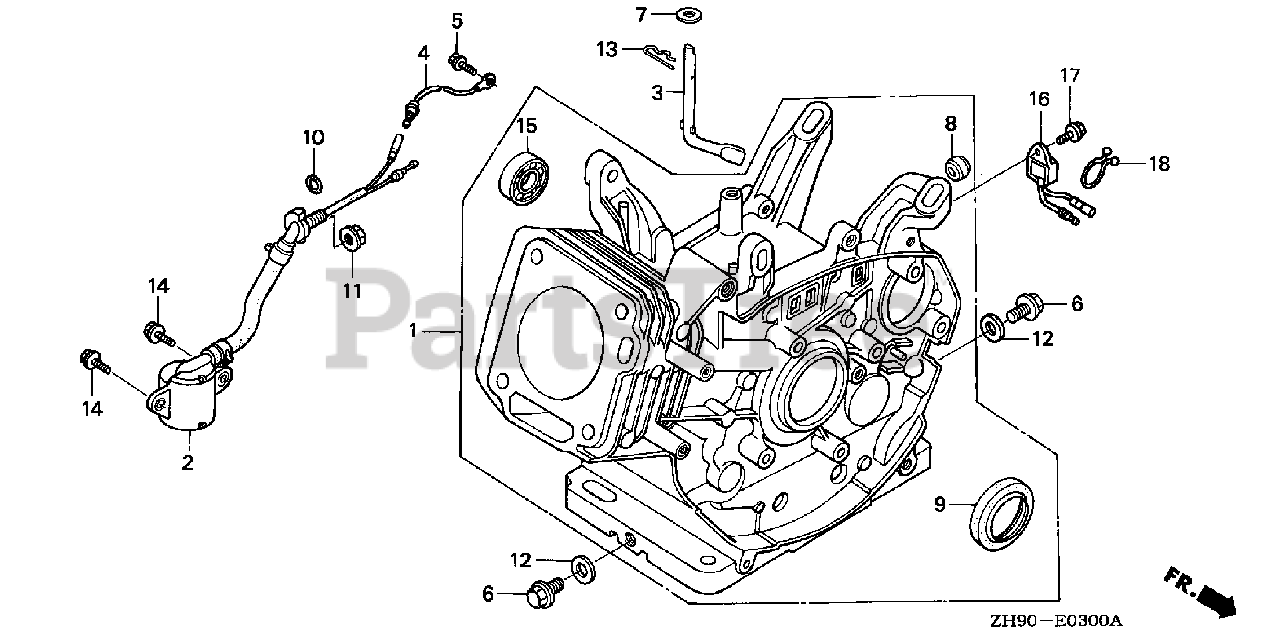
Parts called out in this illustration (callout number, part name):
1	CYLINDER ASSY. (ALERT)
2	SWITCH ASSY., OIL LEVEL
3	SHAFT, GOVERNOR ARM
6	BOLT, DRAIN PLUG
7	WASHER (8.2X17X0.8)
9	OIL SEAL (30X46X8)
10	O-RING (13.5X1.5) (ARAI)
11	NUT, FLANGE (10MM)
12	WASHER, DRAIN PLUG (12MM)
13	PIN, LOCK (10MM)
14	BOLT, FLANGE (6X12)
16	ALERT UNIT, OIL
17	BOLT, FLANGE (6X12) (CT200)
